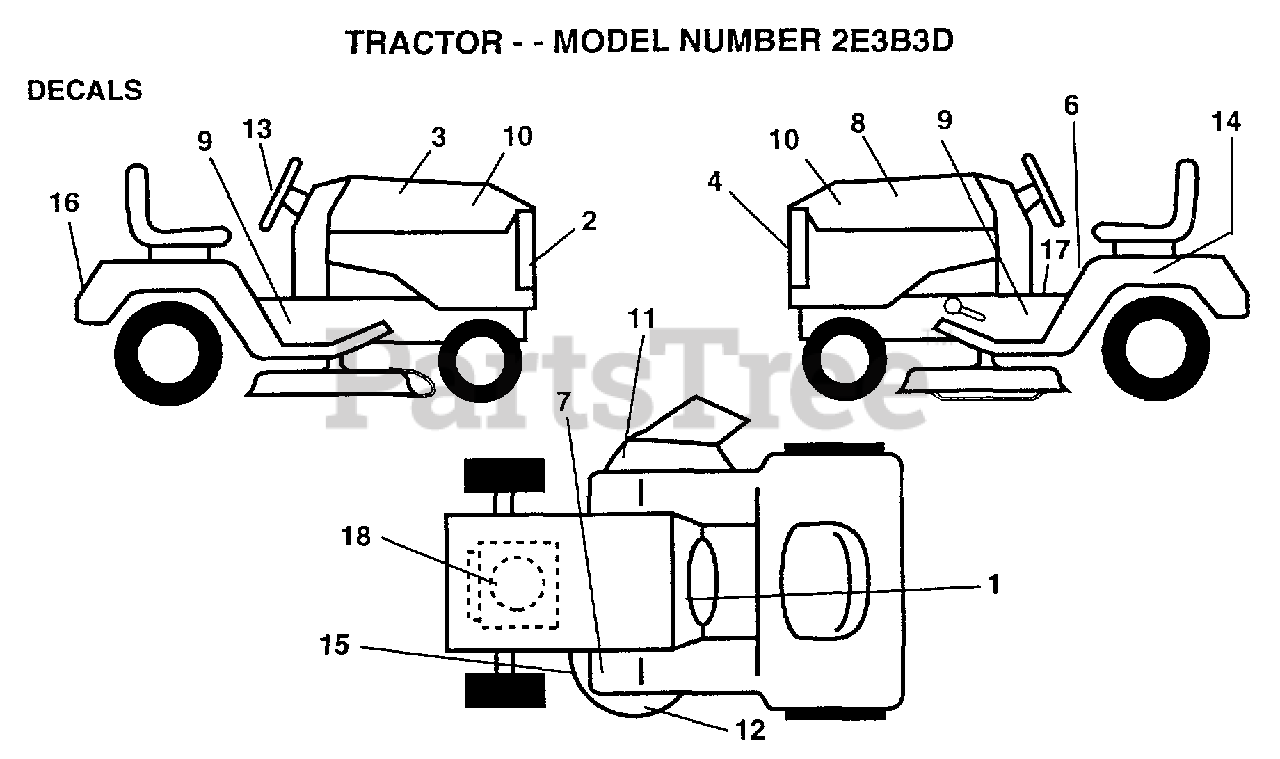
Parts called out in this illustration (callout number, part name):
1	DECAL.DASH.INSTR.
2	GRILL DECAL
3	DECAL HOOD RH RLY
6	DECAL CAUTION
7	DECAL T
8	DECAL HOOD LH RLY
10	DECAL.HOOD.INSERT
11	"DECAL, WARNING"
13	"DECAL,STR WHL"
14	DECAL.BTRY.DANGER
15	DECAL
16	FENDER DECAL
17	DECAL BRAK PARK
18	DECAL, ENGINE
